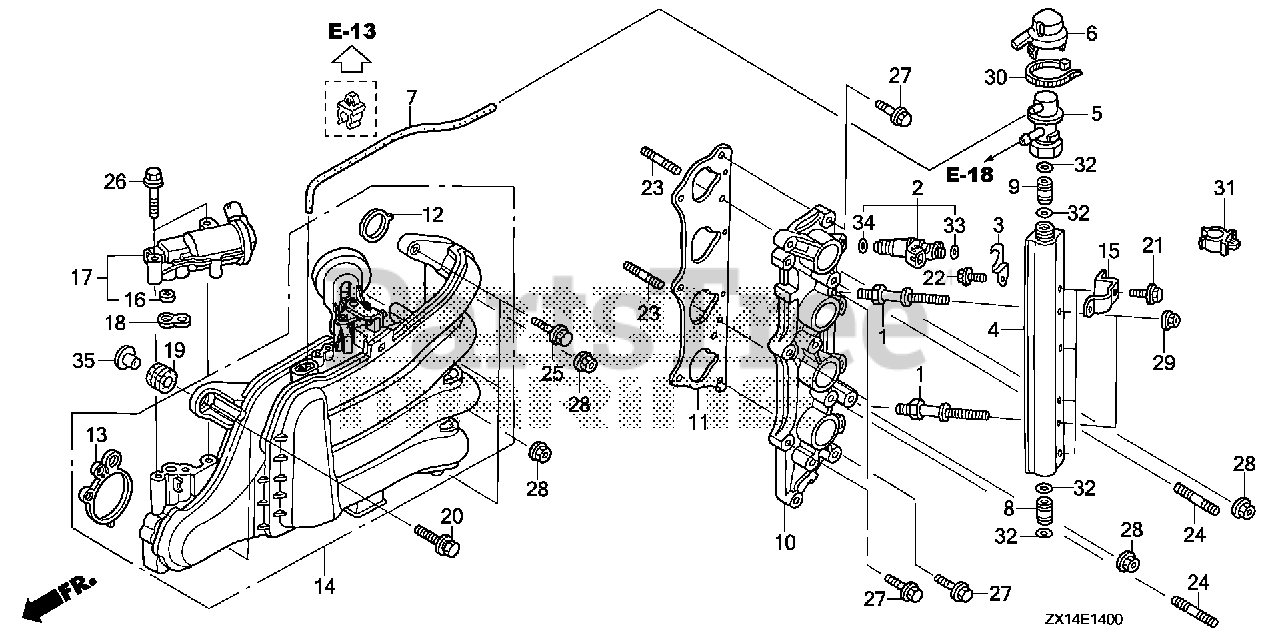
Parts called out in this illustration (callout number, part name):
1	BOLT, FUEL PIPE
2	INJECTOR ASSY., FUEL
3	CLIP, INJECTOR
4	LINE, FUEL
5	REGULATOR ASSY., PRESSURE
6	CAP, REGULATOR
7	TUBE, PRESSURE REGULATOR CONTROL
8	JOINT, FUEL PIPE
9	JOINT, FUEL PIPE
10	BASE, INJECTOR *NH8* (DARK GRAY)
11	GASKET A, INJECTOR BASE
12	GASKET, IN. MANIFOLD
13	GASKET, THROTTLE BODY
14	MANIFOLD, INLET
15	BRACKET A, HARNESS CLIP
16	FILTER, ELECTRONIC AIR CONTROL VALVE (TOYO ROKI)
17	VALVE ASSY., ELECTRONIC AIR CONTROL
18	GASKET, ELECTRONIC AIR CONTROL VALVE
19	RUBBER, FR. CARRIER CUSHION
20	BOLT-WASHER (8X35)
21	BOLT, FLANGE (6X14)
22	BOLT, FLANGE (6X10)
23	BOLT 2, STUD (8X25)
24	BOLT, STUD (8X32)
25	BOLT, FLANGE (8X35)
26	BOLT, FLANGE (8X45)
27	BOLT, FLANGE (8X25)
28	NUT, FLANGE (8MM)
29	NUT, FLANGE (6MM)
30	BAND, HARNESS
31	CLIP, FUEL TUBE (14) (NOT AVAILABLE)
32	O-RING (7.8X1.9) (ARAI)
33	O-RING (7.47X3.6)
34	O-RING (7.45X3.61) (NOK)
35	COLLAR (8.5X14.5)
